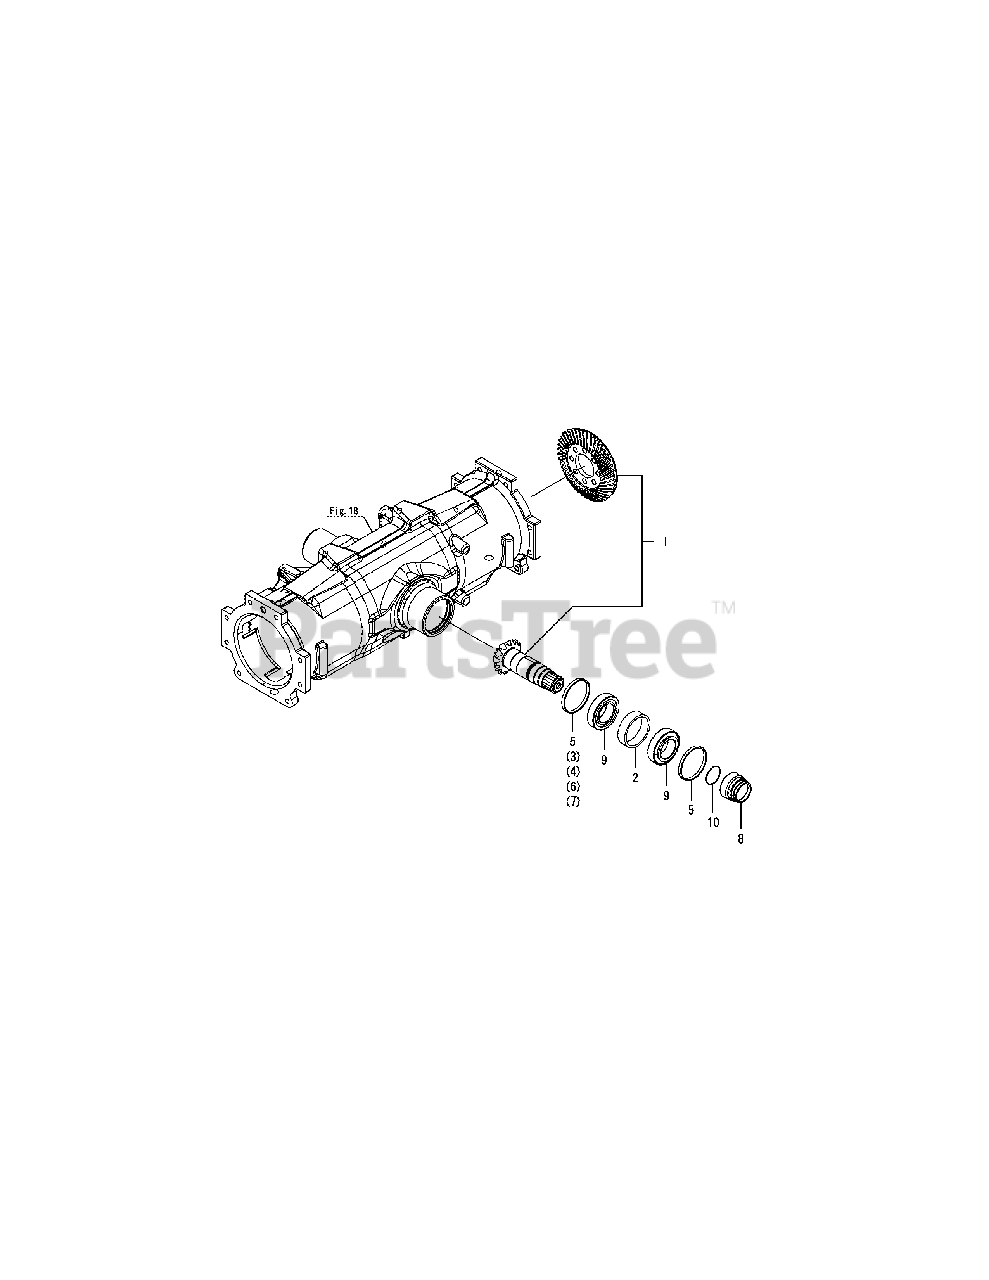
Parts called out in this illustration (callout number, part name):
1	GEAR ASSY, RING
3	COLLAR 58X62X4.8
4	COLLAR 58X62X4.9
5	COLLAR 58X62X5.0
6	COLLAR 58X62X5.1
7	COLLAR 58X62X5.2
9	ROLLER BEARING
10	O-RING, 1A S31.5
